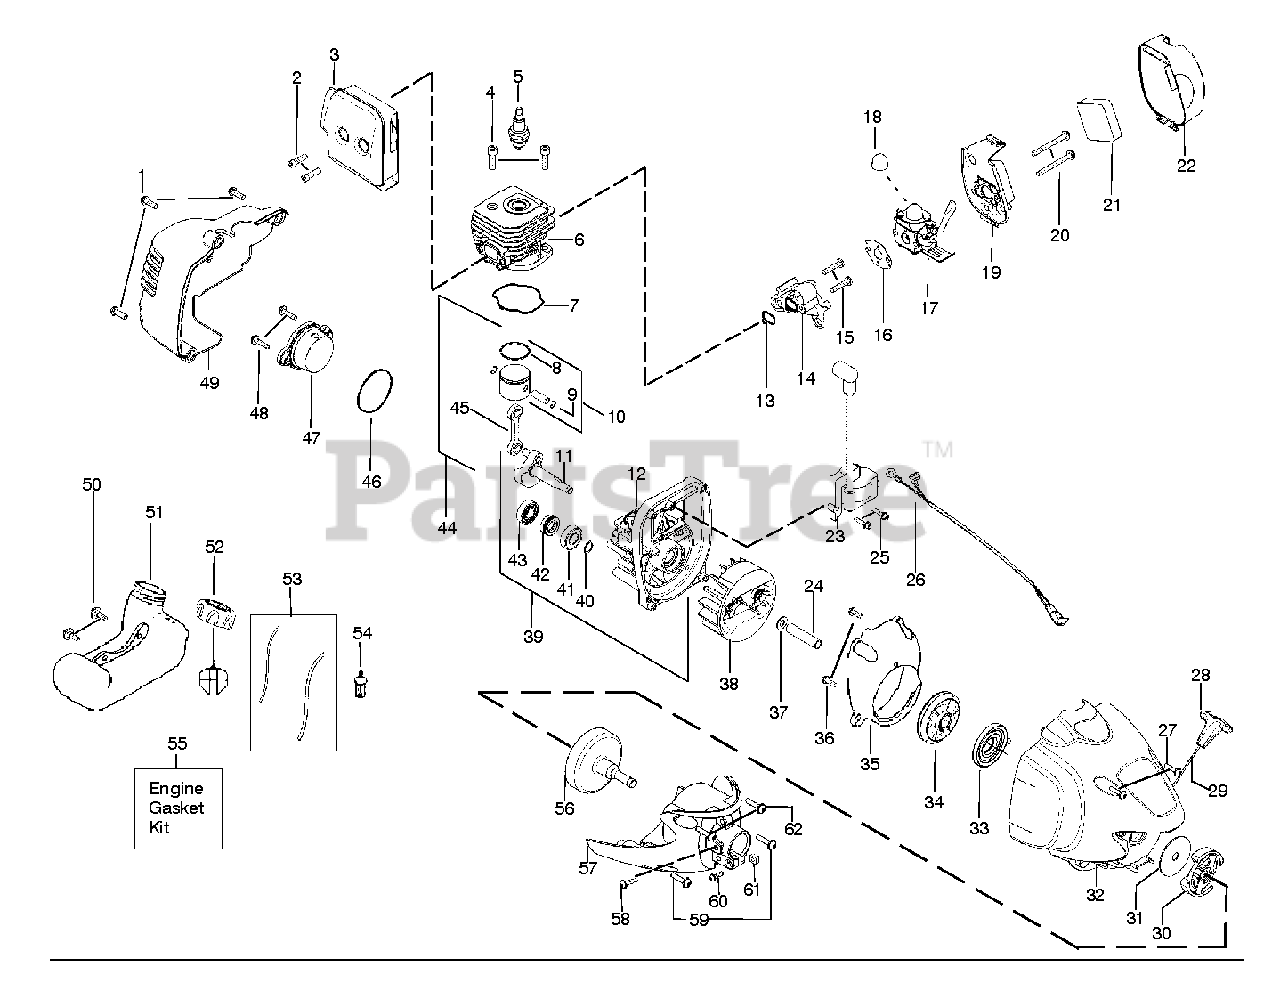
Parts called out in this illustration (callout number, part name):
2	BOLT MUFFLER
3	ASSY MUFFLER SHIELD
5	PLUG-SPARK (RCJ-6Y)
6	CYLINDER MACHINED 25CC LO
8	RING PISTON
9	WRIST PIN RET.
10	PISTON KIT
11	ASSY CRANKSHAFT
12	ASSY CRANKCASE
14	ADAPTOR CARBURETOR
17	KIT CARB ASSY
18	PURGE BULB ZAMA
19	BASE AIR BOX PP GOLD
21	AIR FILTER
22	COVER AIR BOX FE
24	SPACER FLYWHEEL
26	ASSY WIRE SWITCH
28	HANDLE STARTER BLK
29	KIT ROPE
30	ASSEMBLY CLUTCH
31	WASHER-CLUTCH
32	HSG FAN W/EYELET PP GOLD
33	SPRING STARTER SA
34	KIT STARTER PULLEY
35	BAFFLE FAN
37	WASHER CLUTCH
38	ASSY FLYWHEEL
39	ASSY CRANKCASE & CRANKSHAFT
40	RETAINING RING
41	OUTER BEARING
43	BEARING
44	PISTON KIT
45	KIT-CONN ROD ASSY
47	ASSY REAR PLUG
49	SHROUD REAR BLACK
50	SCREW FUEL TANK RETAINER
51	ASSY FUEL TANK LOW PERM
52	FUEL CAP ASSY
54	FUEL PICK-UP ASSY
55	KIT GASKET 25CC
56	ASSY CLUTCH DRUM W/ADPT
57	ASSY CLUTCH COVER
59	SCREW-10-24 X 1" (TAP.)
60	SCREW 12-24 X 5/8
61	NUT SQUARE 12-24
